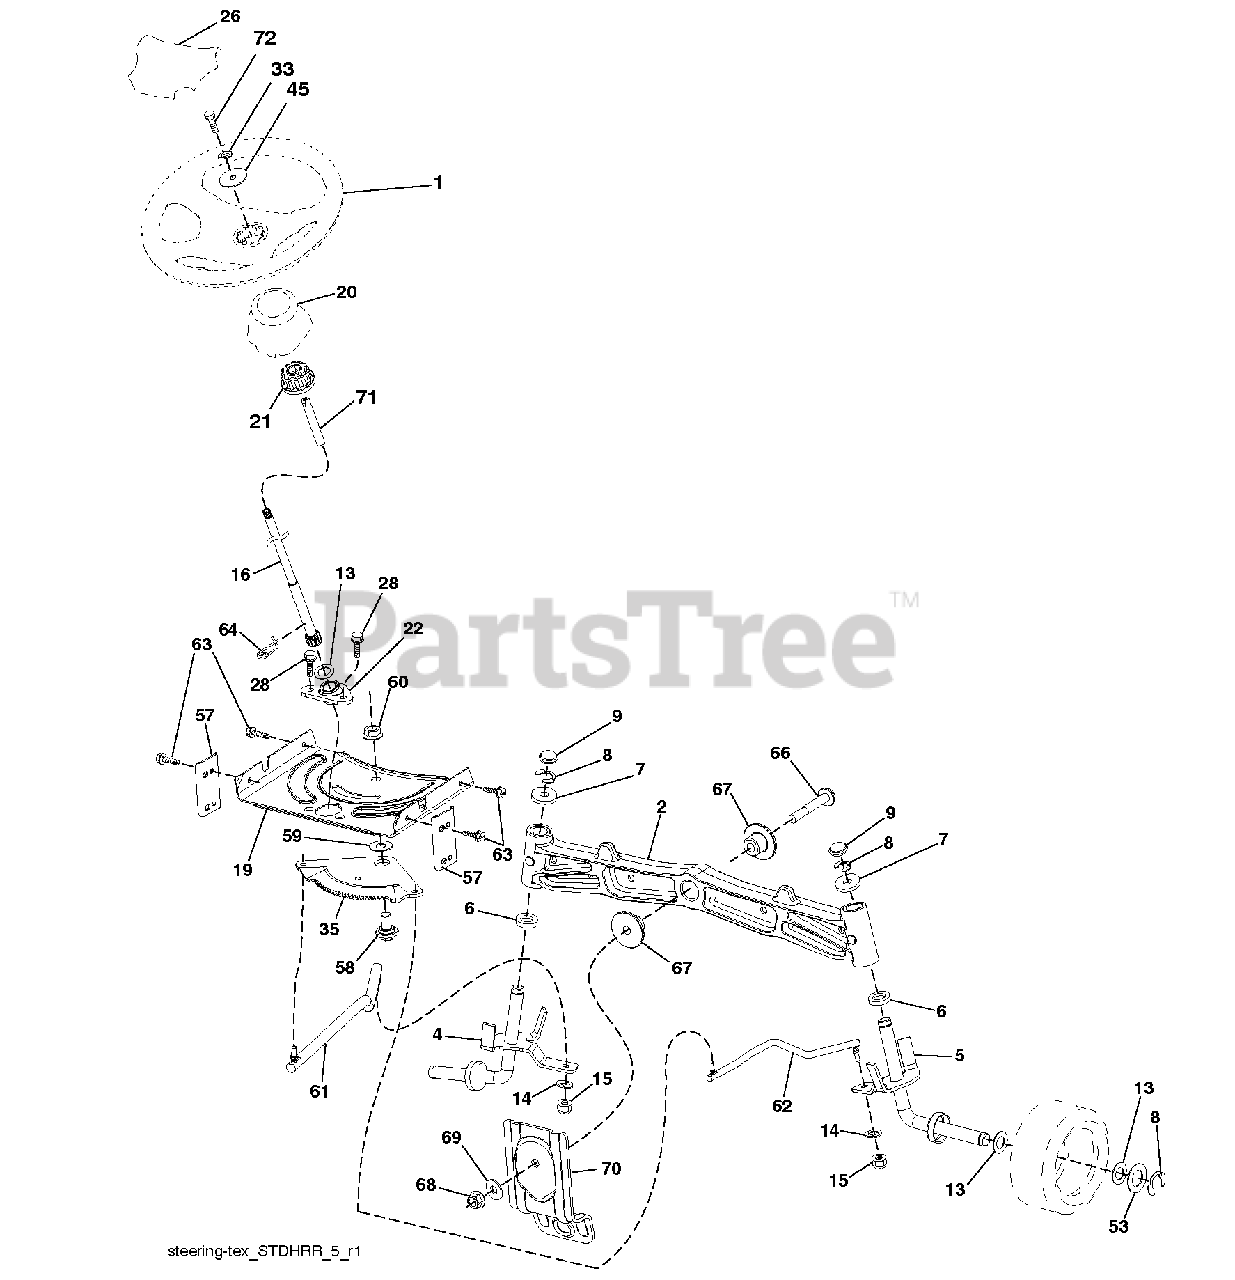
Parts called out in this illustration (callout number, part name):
1	Wheel, Steering
2	Axle Asm., Front
4	Spindle Asm., LH
5	Spindle Asm., RH
6	Washer Thrust 0.75 x 1.23
7	Washer 25/32 x 1-5/8 x 16 Ga.
8	Ring, Clip #T5304-75
9	Cap, Spindle
13	Washer 25/32 x 1-1/4 x 16 Ga.
14	Washer Lock 3/8
15	Nut, Crown Lock 3/8-24 unf
16	Shaft Steering
19	Plate Steering
20	Boot, Steering
21	Adapter, Wheel Steering
22	Strg. Supt. Lower
26	Insert, Wheel Steering
28	Screw 3/8-16 x 3/4
33	Washer Lock 5/16
35	Gear, Sector Plate
45	Washer 11/32 x 2-3/8 x 12 Ga.
53	Washer Hardened .793 x 1.637 x .060
57	Bracket Upstop
58	Bolt Shoulder Sector Pivot CFM
59	Washer Thrust Sector Steering
60	Nut Flange Lock 5/8-11
61	Draglink, LH
62	Draglink, RH
63	Screw 5/16-18 x 3/4
64	Retainer Clip Spring Steering
66	Bolt Hex Fghd 7/16-14 x 3 Serr
67	Bushing PM Front Axle
68	Nut Lock Flange 7/16-14 Gr. 5
69	Washer 1.5 x .505 x .118
70	Bracket Deck Susp. Front
71	Shaft Ext. Steering
72	Bolt 5/16-18 x 4 W/Patch
